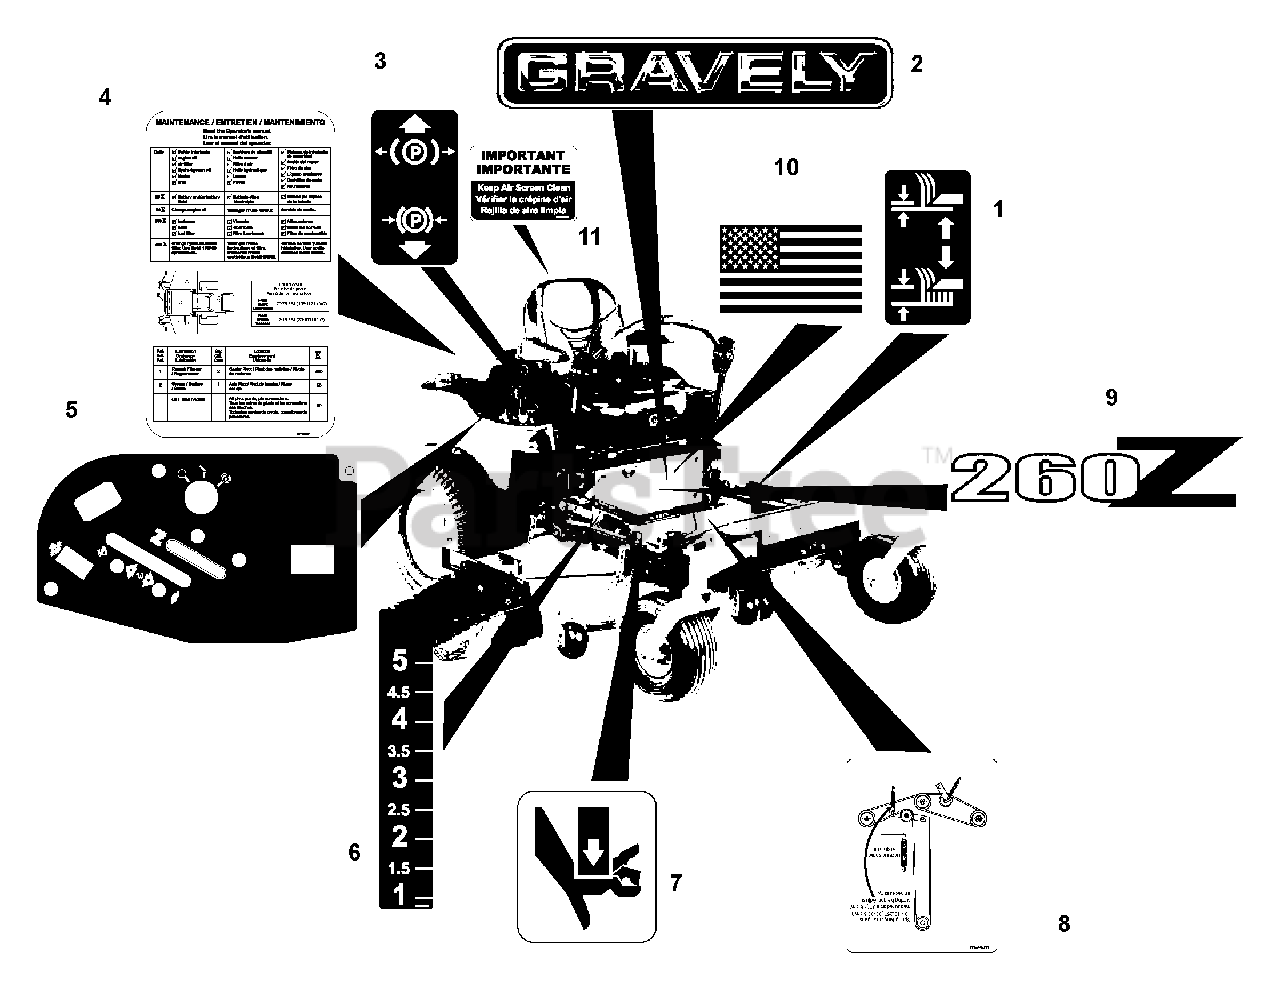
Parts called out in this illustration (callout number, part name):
1	Decal, Lift Lever (992124, 128, 129, 132, 133, 135, 139)
2	Decal, 15 in. Gravely Logo
3	Decal, Parking Brake Lever
4	Decal, Service Instructions
5	Decal, Control Panel (992113, 117, 124, 130, 134, 135, 139)
5	Decal, Control Panel (992111, 115, 127, 128, 129, 131, 132, 133, 145)
6	Decal, Height of Cut (992124, 128, 129, 132, 133, 135, 139)
6	Decal, Height of Cut (992111, 113, 115, 117, 127, 130, 131, 132, 134, 145)
7	Decal, Pinch Point (992124, 128, 132, 135, 139, 129, 133)
8	Decal, Belt Diagram
9	Decal, PM-260Z (992115, 117, 131, 132, 133, 134, 135, 145)
9	Decal, PM-272Z (992124, 139)
9	Decal, PM-252Z (992111, 113, 127, 128, 129, 130)
10	Decal, American Flag
11	Decal, Warning Clean Debris (992113, 117, 124, 130, 134, 135, 139)
